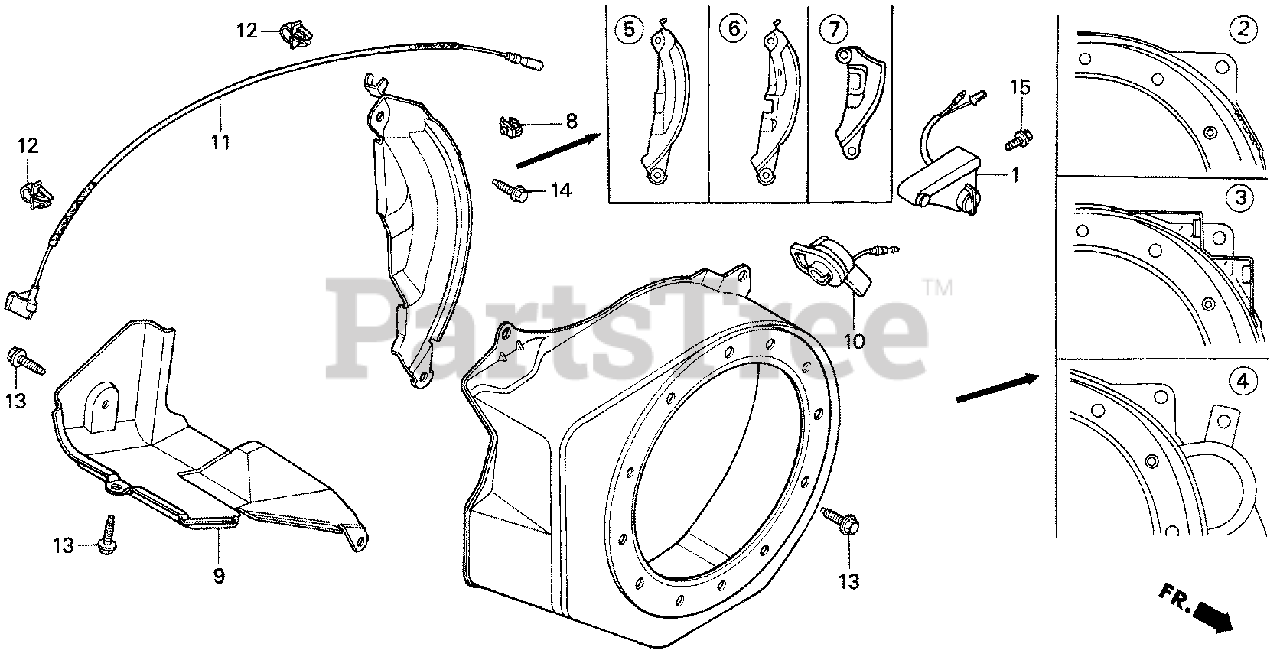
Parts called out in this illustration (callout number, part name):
4	COVER, FAN (STARTER MOTOR & CONTROL BOX)
7	PLATE, SIDE (STARTER MOTOR)
9	SHROUD
11	WIRE, STOP SWITCH
12	HOLDER, STOP SWITCH WIRE
13	BOLT, FLANGE (6X12) (CT200)
14	BOLT, FLANGE (6X25)
